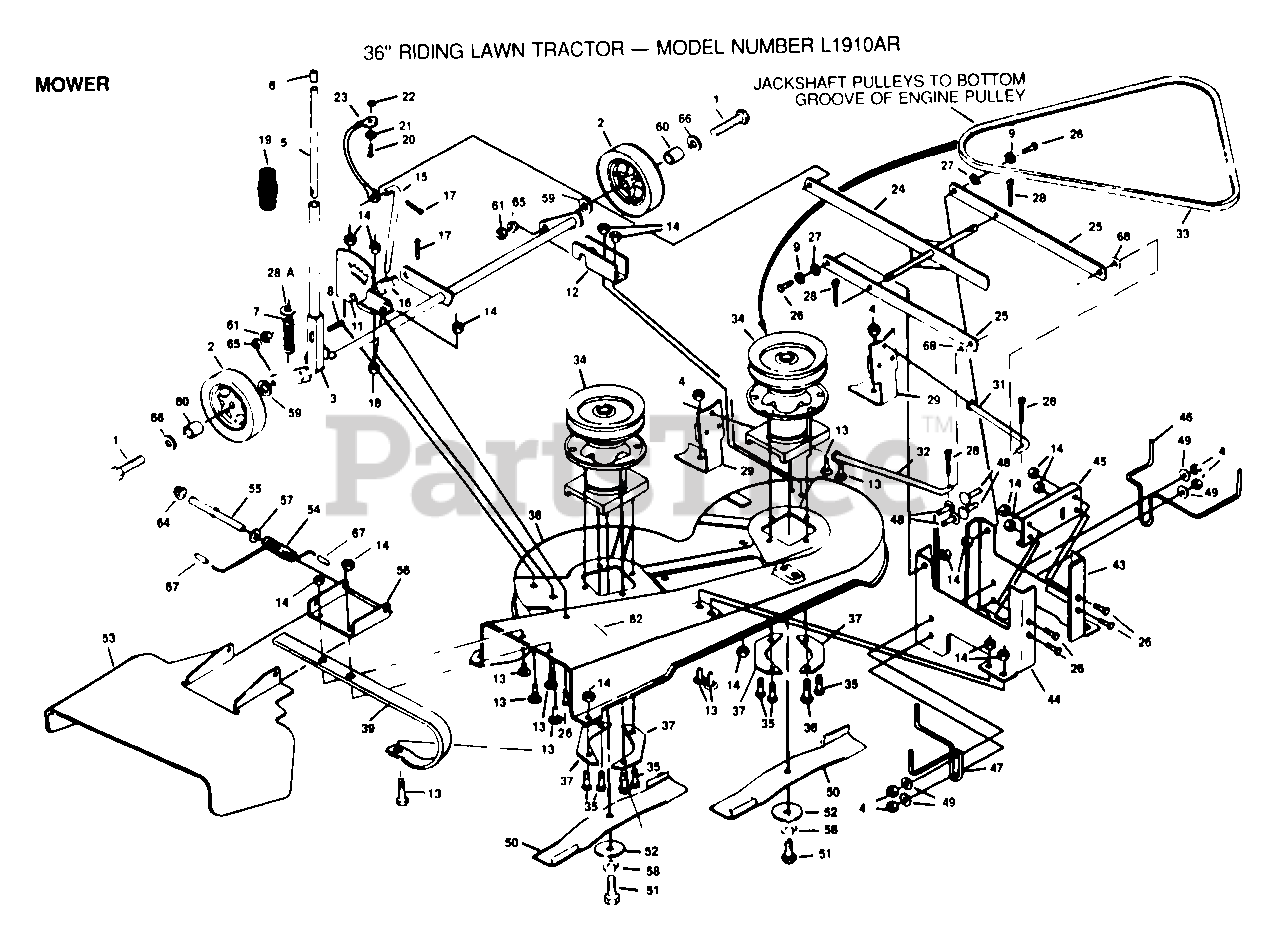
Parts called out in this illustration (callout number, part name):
1	"BOLT,HEX"
2	WHEEL.GAGE.STL.WH
3	PIVOT ROD LT
5	ROD PLUNGER T
9	WASHER M
11	QUADRANT ASSY
12	PIVOT ROD SUP T
13	BOLT
18	NUT
19	GRIP LT
21	WASHER
23	SWAY CABLE
24	PARALLEL ROD ASSY
25	PARALLEL LINK T
26	BOLT
28	PIN COTTER 1/8
28A	WASHER
28B	BOLT
29	BRAKE.ASSY.LT.
31	ROD.BRAKE.BLADE.L
32	ROD.BRAKE.BLADE.R
33	V BELT LT
34	"JACKSHAFT.38""LT"
35	SCREW
36	SCREW
37	SUPPORT PLATE LT
48	BOLT
51	BOLT.3/8-24X1-1/2
52	WASHER T
55	HINGE ROD
57	WASHER
59	WASHER
60	BUSHING M
61	GRIPCO NUT
62	DECAL HYT
64	NUT PUSH M
66	WASHER
67	CAP-SLEEVE LT
